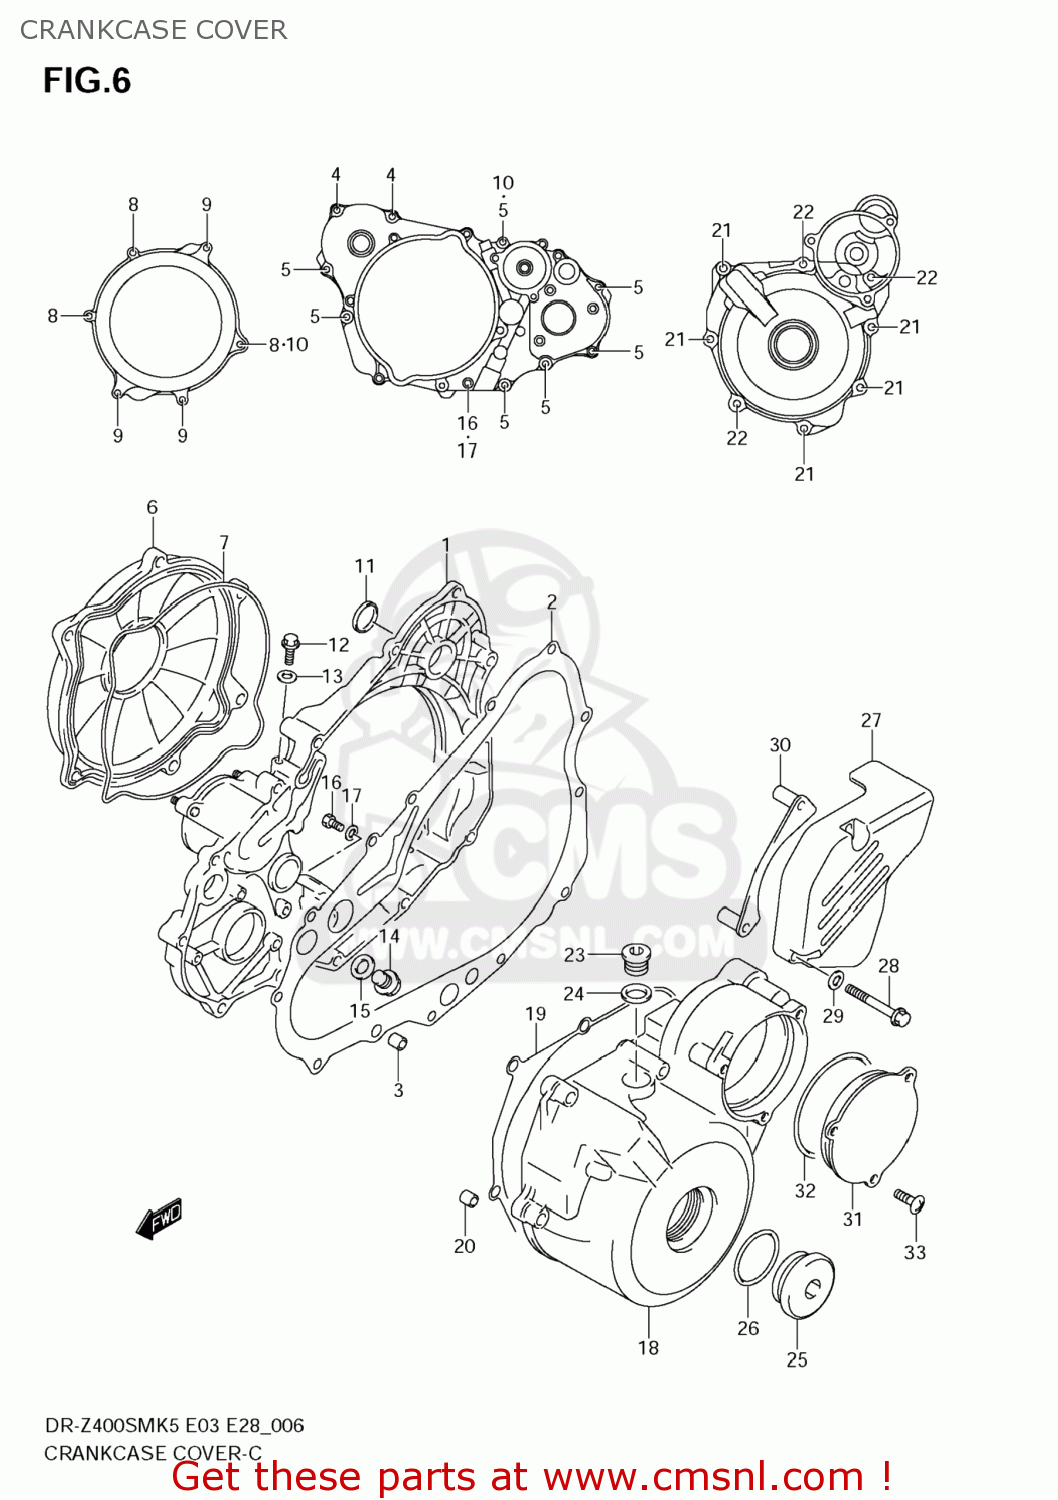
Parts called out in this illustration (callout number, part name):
1	COVER,CLUTCH INNER
2	GASKET,CLUTCH COVER (NAS)
3	PIN
4	BOLT
5	BOLT
6	COVER,CLUTCH OUTER
7	O RING,CLUTCH COVER OUTER
8	BOLT
9	BOLT
10	GASKET(5.8X13X1.2) (NAS)
11	PLUG,CLUTCH COVER KICK
12	BOLT
13	GASKET(5.8X13X1.2) (NAS)
14	PLUG(12X10)
15	GASKET(12.1X16.2X3.7) (NAS)
16	BOLT
17	GASKET(6.2X11X1).2 (NAS)
18	COVER,MAGNETO
19	GASKET,MAGNETO COVER (NAS)
20	PIN
21	BOLT
22	BOLT
23	PLUG,14X12
24	GASKET(13.8X18.8X4.8) (NAS)
25	PLUG(SILVER)
26	O RING(D:3.1,ID:32.7)
27	COVER,ENGINE SPROCKET
28	BOLT
29	WASHER(6.5X14X2)
30	PLATE,FR CHAIN GUIDE
31	COVER,STARTER IDLE GEAR
32	O RING(D:2.6,ID:67.1)
33	SCREW
